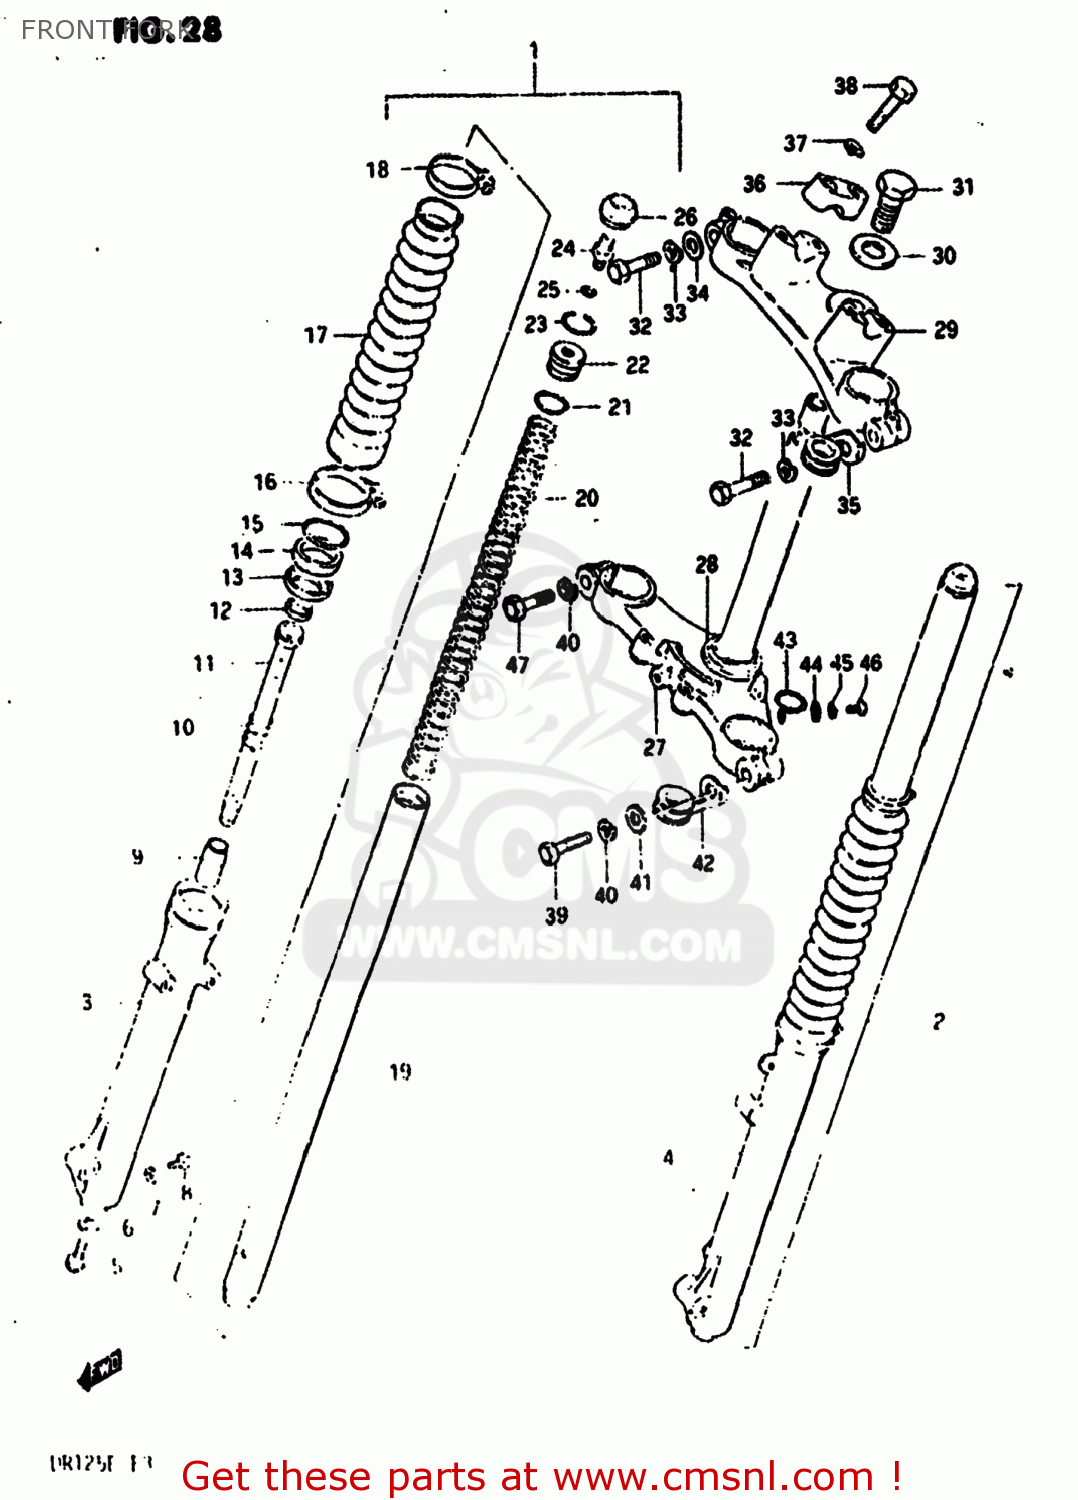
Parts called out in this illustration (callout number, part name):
1	DAMPER ASSEMBLY,RIGHT
2	DAMPER ASSEMBLY,LEFT
3	TUBE,FORK,OUTER,RIGHT
4	TUBE,OUTER,LEFT
5	BOLT(8X27)
6	GASKET (NAS)
7	GASKET,DRAIN,PLUG (NAS)
8	BOLT
9	PIECE,OIL LOCK
10	SPRING,REBOUND
11	CYLINDER,FR FORK
12	RING,PISTON
13	SPACER
14	OIL SEAL,FRONT FORK
15	RING,OIL SEAL STOPPER
16	BAND,FR FORK BOOT
17	BOOT,FR FORK COVER
18	BAND,BOOT,UPPER
19	TUBE,FORK INNER
20	SPRING,FRONT FORK
21	O RING
22	SEAT,SPRING
23	RING,STOPPER
24	VALVE,AIR
25	O-RING
26	CAP,FRONT FORK
27	STEM,STEERING
28	RACE,STEERING OUTER LWR
29	HEAD,STEERING STEM
30	WASHER,STEM HEAD(10.5X30X3.2)
31	BOLT,STEERING STEM HEAD
32	BOLT
33	LOCK WASHER
34	WASHER
35	GUIDE,CABLE
36	HOLDER,HANDLEBAR
37	LOCK WASHER
38	BOLT
39	BOLT 12X45
40	WASHER,LOCK 12
41	WASHER
42	GUIDE,CABLE
43	CLIP
44	WASHER
45	LOCK WASHER
46	SCREW 6X12
47	BOLT
